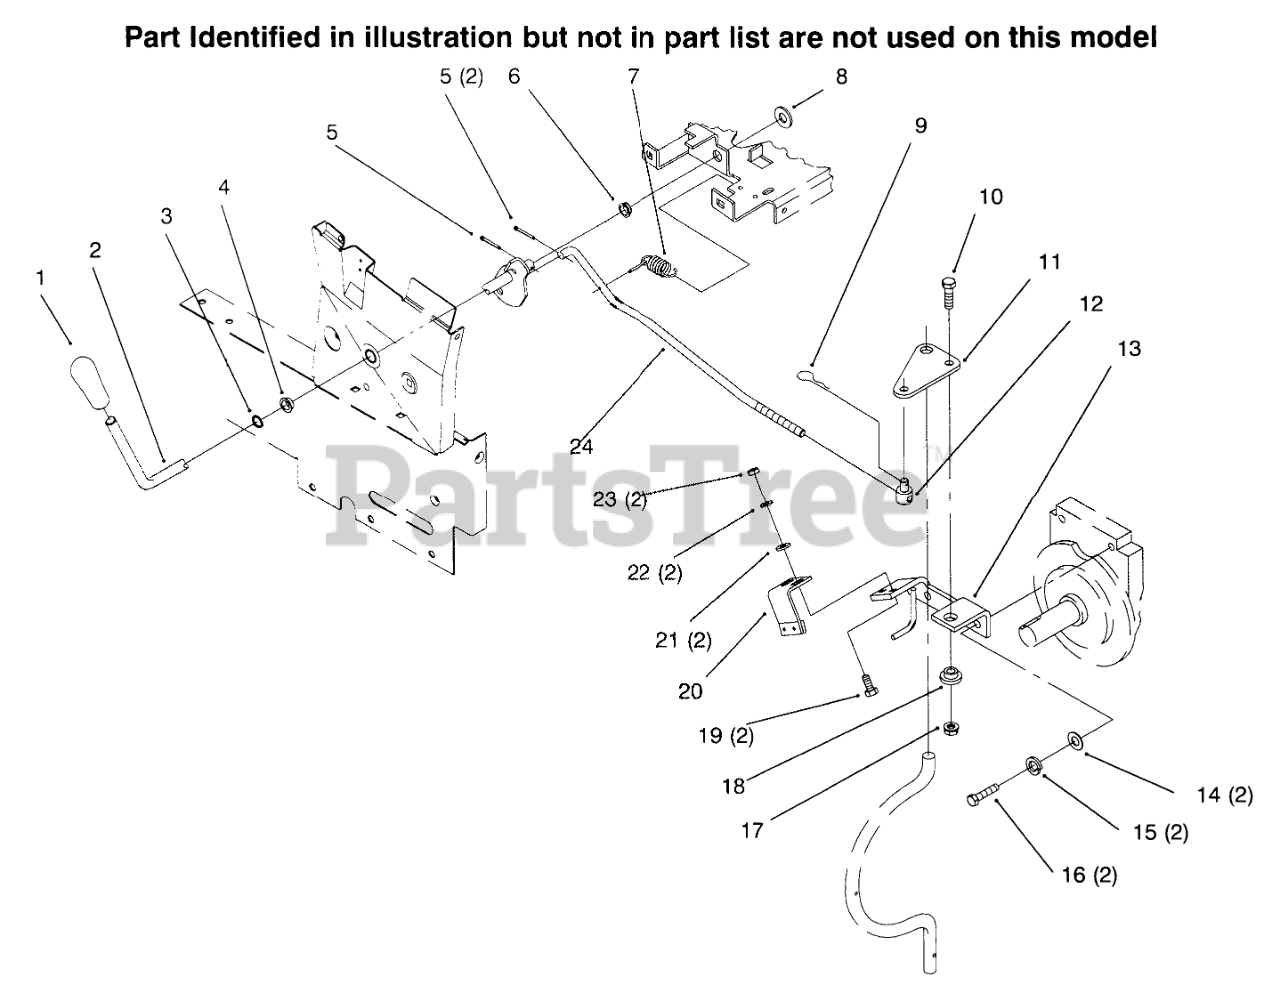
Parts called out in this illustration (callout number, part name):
2	PTO CLUTCH LEVER ASM
3	RING-EXT GRIP
4	BUSHING-NYLINER
5	PIN-COTTER
6	NYLINER BUSHING
7	SPRING
8	SHIM-WASHER
9	PIN-HAIR
10	SCREW-HH
11	PLATE
12	TRUNNION
13	Bracket
14	WASHER-FLAT
15	WASHER-LOCK
16	SCREW-HH
17	NUT-LOCK, NI
18	SPACER-LIFT LINK
19	SCREW-CARR
20	ASM-Bracket
20	BRAKE ASM
21	WASHER-FLAT
22	WASHER-LOCK
23	NUT-JAM
24	ROD-PTO CLUTCH
